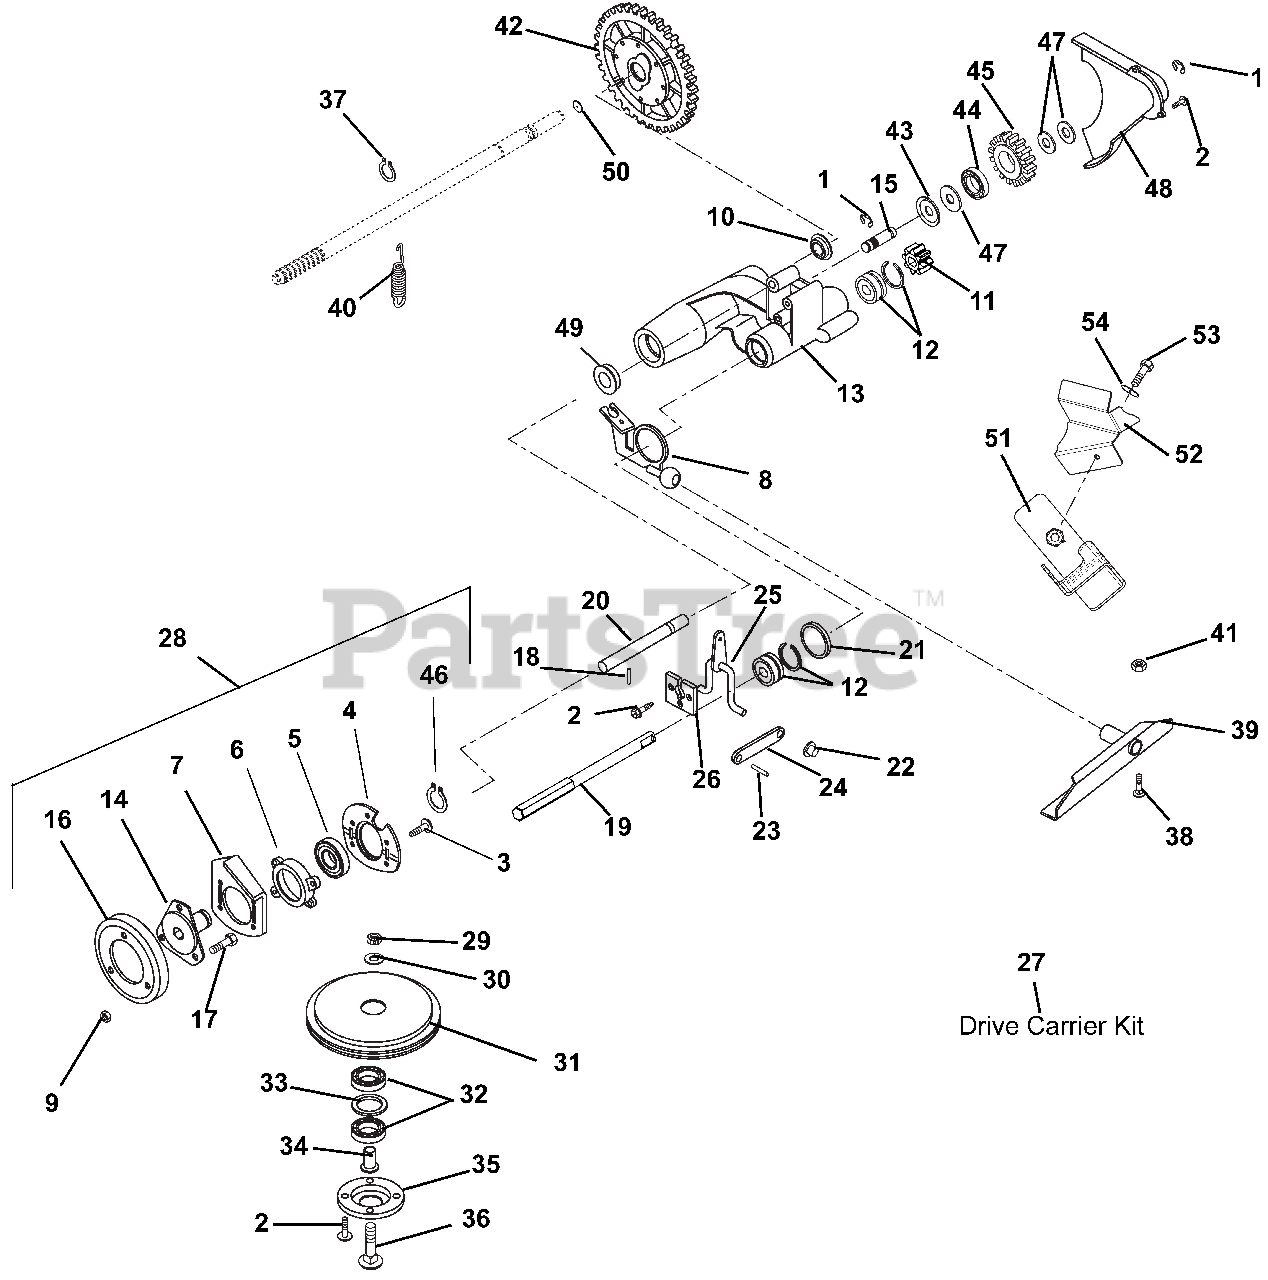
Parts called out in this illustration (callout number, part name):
1	RG-RTNG-EXT .438X.035
2	@SCR-TAP 12-24X.50 HWH TR YWZC
3	SCR-TAP 5HX-0.8X16MM H-FL-YWZC
4	BEARING RETAINER
5	BRG-BALL 1.0X2.0X.56 (1641)
6	BEARING RETAINER
7	PLATE, BEARING
8	ACTUATOR, WBLM DRIVE
9	@NUT-LK-CTR .25-20 YWZC
10	BRG-BALL .625X1.378X.44
11	PINION, D-SHAFT
12	BRG-BALL .50X1.38X.438 SEALED
13	DRIVE MOUNT
14	FRICTION WHEEL HUB
15	IDLER SHAFT
16	DISC, FRICTION - 730 MAT'L
17	@BLT-HEX .25-20X.50 GR5 YWZC
18	PIN-ROLL .188X.88
19	SHAFT, FRICTION DISK
20	ROD - GUIDE
21	WSHR-FL-STL 1.390X2.00X.020 PL
22	PUSH NUT, .25
23	PIN-ROLL .125X.50
24	SHIFT LINK
25	SHIFT ARM WELDMENT
26	RETAINER PLATE
27	KIT, LM DRIVE CARRIER
28	KIT, COM. DRIVE CONVERSION
29	@NUT-LK-CTR .31-18 YWZC
30	WSHR-FL-STL .328X.87X.179 YWZC
31	FRICTION SHEAVE
32	BRG-BALL .625X1.375X.43
33	WSHR-FL-STL 1.062X1.344X.032PL
34	SPINDLE - BEARING
35	RETAINER - BEARING
36	@BLT-RDHDSQNK .31-18X1.75 G5YZ
37	RG-RTNG-EXT .579X.035
38	@BLT-RHDSSQNK .31-18X.62 G5YZ
39	PIVOT CHANNEL WELDMENT
40	SG-TENS .051X.60X2.25 WLD 7.0
41	@NUT-LK-TOP-FLG .31-18 YWZC
42	DIFFERENTIAL ASSEMBLY
43	RETAINER
44	BRG-BALL .500X1.38X.437
45	IDLER GEAR
46	RG-RTNG-EXT 1.00X.042
47	WSHR-FL-STL .52X.827X.062 YWZC
48	COVER, GEAR
49	BRG-BALL .625X1.383X.50
50	WSHR-FL-STL .630X1.250X.062 YZ
51	WLDMT, BELT COVER MOUNTING
52	BRKT, BELT COVER
53	@BLT-HEX .31-18X.50 GR5 YWZC
54	@WSHR-FL-STL.344X.688X.065YWZC
